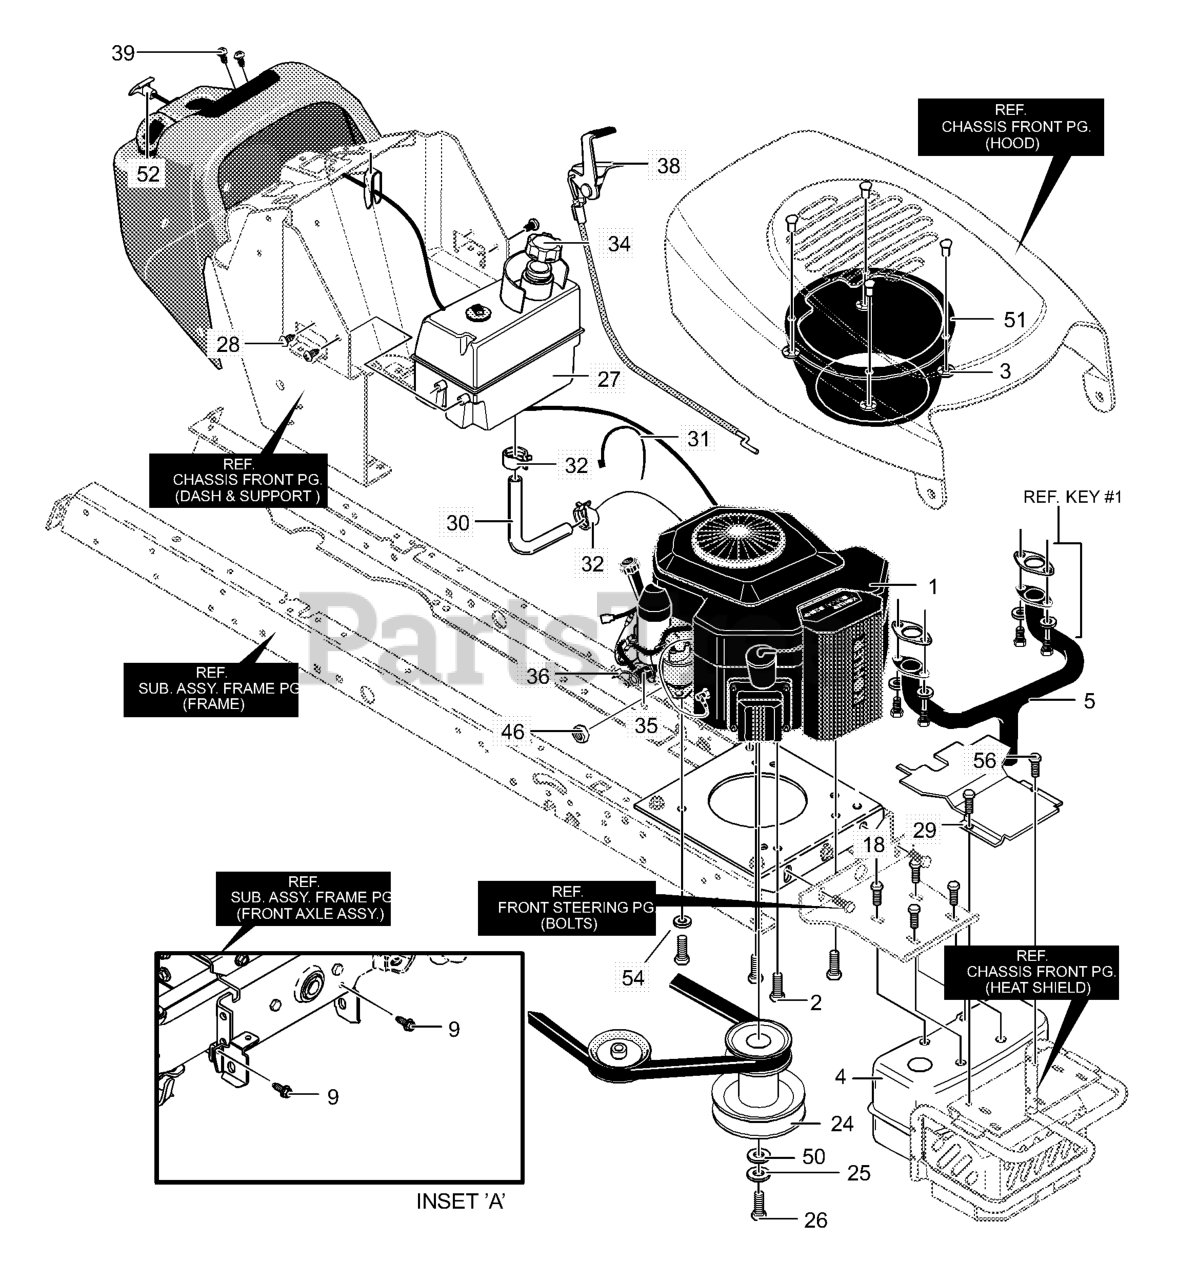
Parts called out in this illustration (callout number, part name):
1	ENGINE
2	BOLT
3	PUSHNUT
4	MUFFLER, TWIN-CYLINDER
5	EXHAUST MANIFOLD
18	SCRW
24	PULLEY, STACK
25	WASHER
27	FUEL TANK
29	SHIELD, HEAT
30	TUBING
31	TIE, CABLE
32	CLAMP, FUEL LINE
34	FUEL CAP
35	OIL DRAIN VALVE ASSEMBLY
36	CAP, OIL DRAIN VALVE
38	THROTTLE CONTROL
46	NUT, 1/4-20
51	PLENIUM
52	CHOKE CONTROL
53	CLIP, CHOKE CONTROL
54	WASHER
56	SCREW
